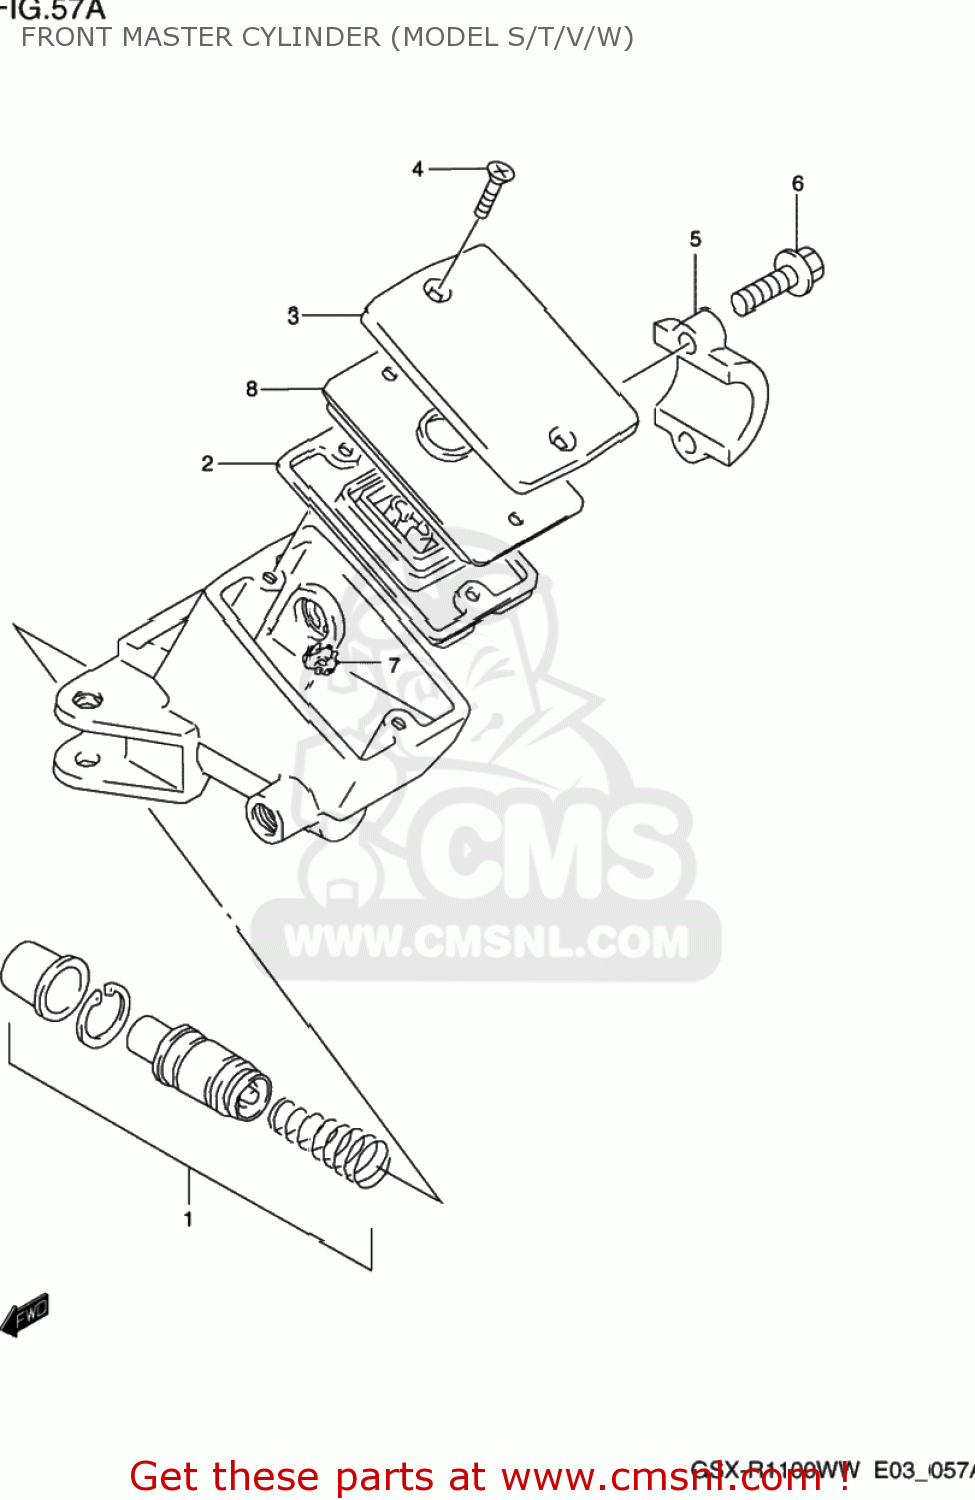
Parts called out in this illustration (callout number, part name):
1	PISTON & CUP SET
2	3
3	CAP
4	SCREW
5	HOLDER
6	BOLT(6X25)
7	PROTECTOR
8	PLATE,DIAPHRAGM
